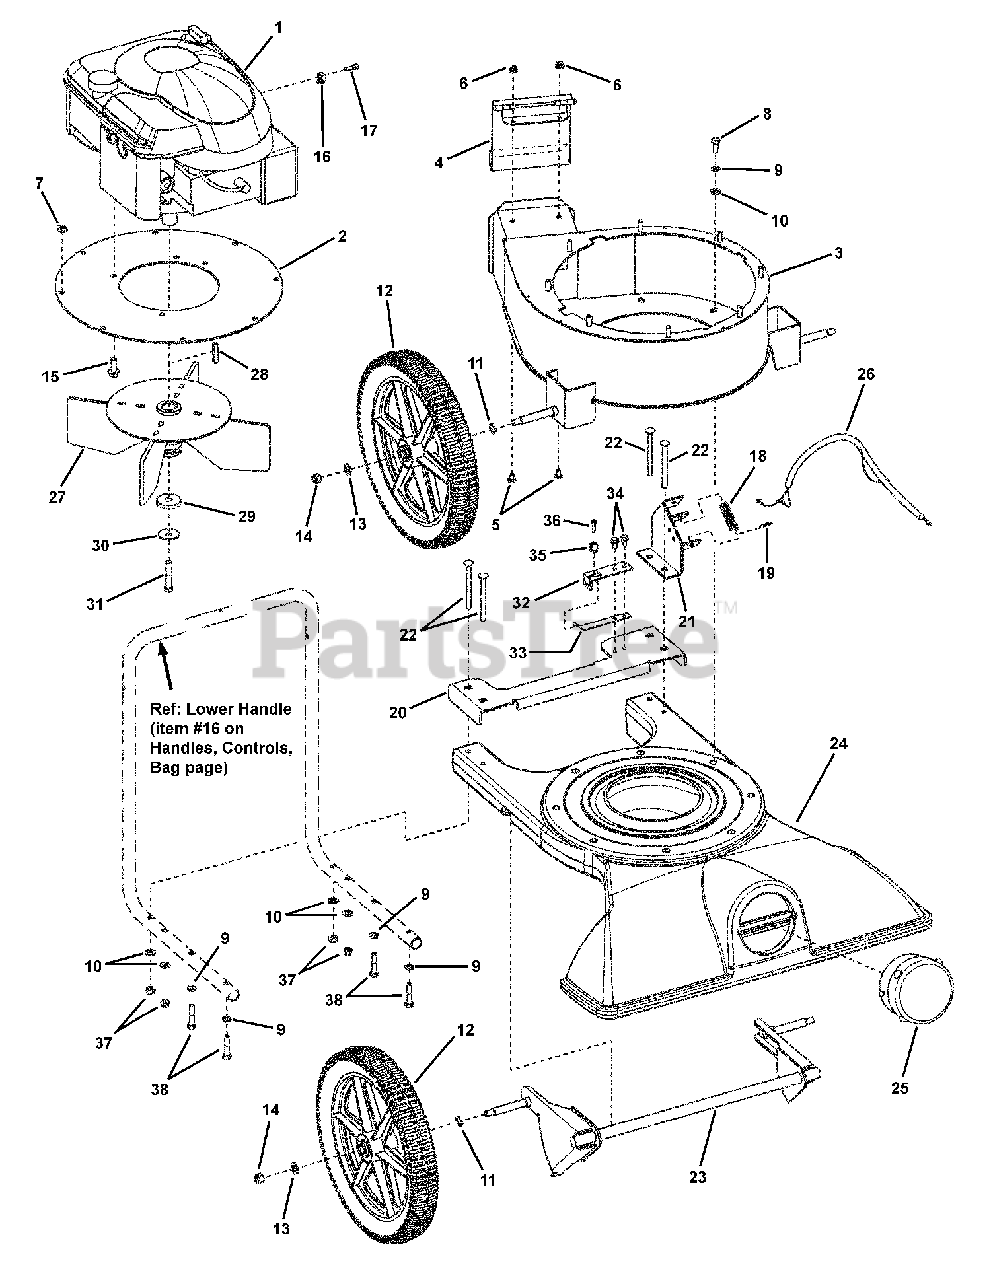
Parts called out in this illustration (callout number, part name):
1	* ENGINE, 6.5HP B&S Quantum Modular XRM, Recoil Start, 123K02-0126-E1
1	* ENGINE, 6.5HP B&S Quantum Modular XRM, Stop Control, 124K02-0140-B1
1	* ENGINE, 6.5GT B&S 650 Series, Stop Control, 124T02-0115-B1
2	PLATE, Engine Base Vacuum Universal
3	WELDMENT, Upper Housing
4	ASSEMBLY, Hinge Door
5	BOLT, 1/4-20 x 1/2" Short Neck Carriage, GR 5
6	NUT, 1/4-20 Hex Flange Lock
7	NUT, 5/16-18 Hex Flange Lock, GR 5
8	SCREW, 5/16-18 x 3/4" Hex Head Cap, GR 5
9	WASHER, 5/16" Split Lock
10	WASHER, 5/16" Flat
11	WASHER, 1/2" Wave
12	WHEEL ASSEMBLY, 14.00 x 2"
13	WASHER, 3/8" SAE Flat
14	NUT, 3/8-16 Nyloc
15	SCREW, 3/8-16 x 1" Hex Washer Self-Tap
16	CLAMP, Casing
17	SCREW, #10-32 x .62" Hex Head Self-Tap
18	SPRING, Compression
19	HAIRPIN, 29/32" Cotter
20	PLATE, Reinforcing
21	WELDMENT, Cable Anchor
22	BOLT, 5/16-18 x 3-1/2" Short Neck Carriage, GR 5
23	WELDMENT, Axle Ass'y, Drag Link
24	HOUSING, Lower
25	PLUG, Hose Port
26	WIRE HARNESS, Interlock
27	WELDMENT, Impeller
28	KEY, 1/4" Square x 1-7/16" long
29	WASHER, .468 I.D. x 1-5/8" O.D. x 1/4" thick
30	WASHER, Cone
31	SCREW, 3/8-24 x 2" Hex Head Cap, GR 5
32	BRACKET, Interlock
33	SPRING, Interlock
34	SCREW, 1/4-20 x 1/2" Hex Washer Self-Tap
35	INSULATOR
36	SCREW,# 8-18 x 3/4 Sheet Metal
37	NUT, 5/16-18 Hex Nyloc
38	SCREW, 5/16-18 x 1-1/2" Hex Head Cap, GR 5
